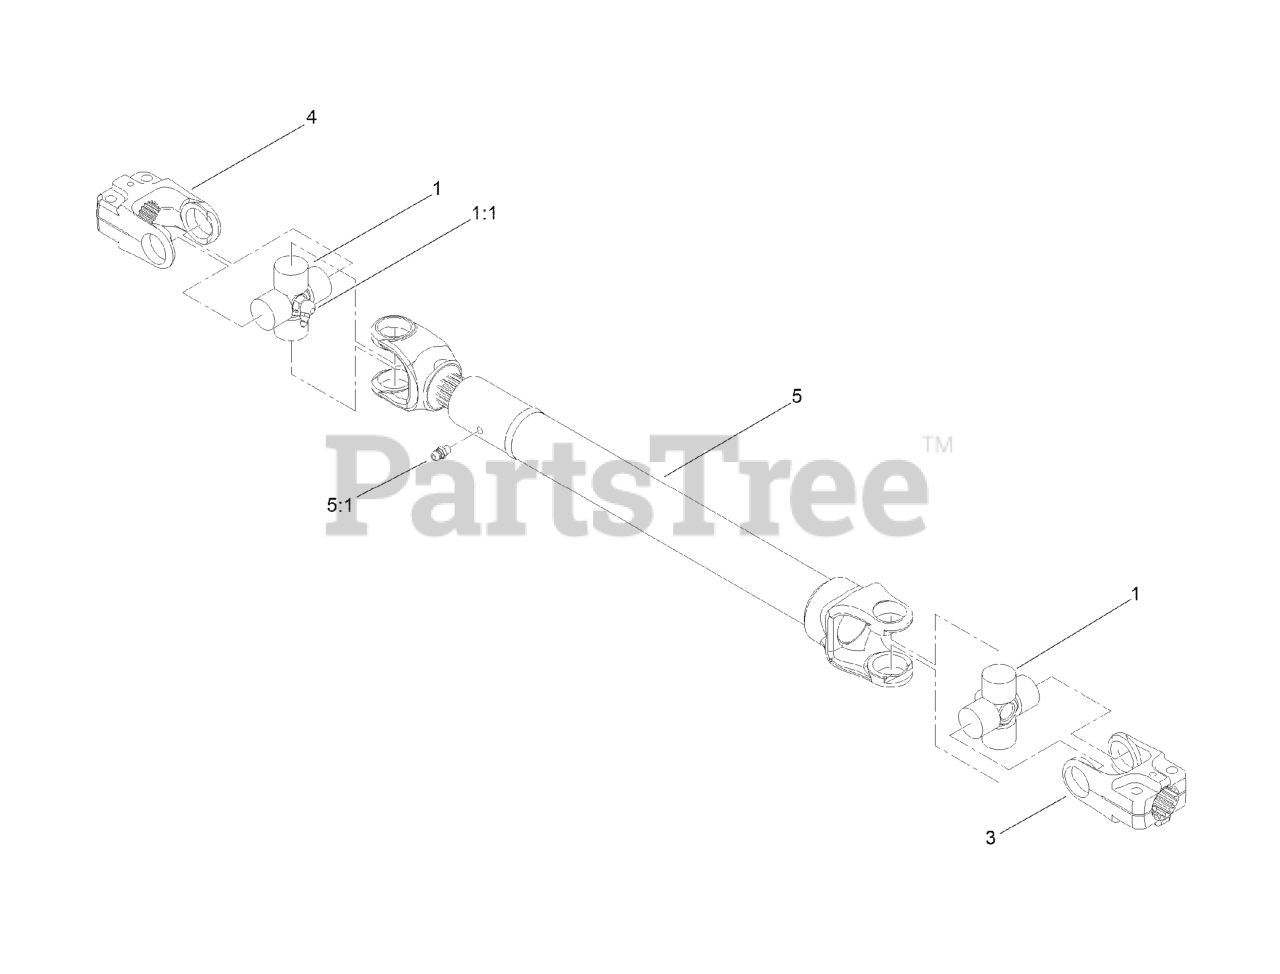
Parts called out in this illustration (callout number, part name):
1	CROSS AND BEARING KIT
1:1	FITTING-GREASE
3	YOKE-END
4	YOKE-END
5	Tube-Yoke, Slip
5:1	FITTING-GREASE
